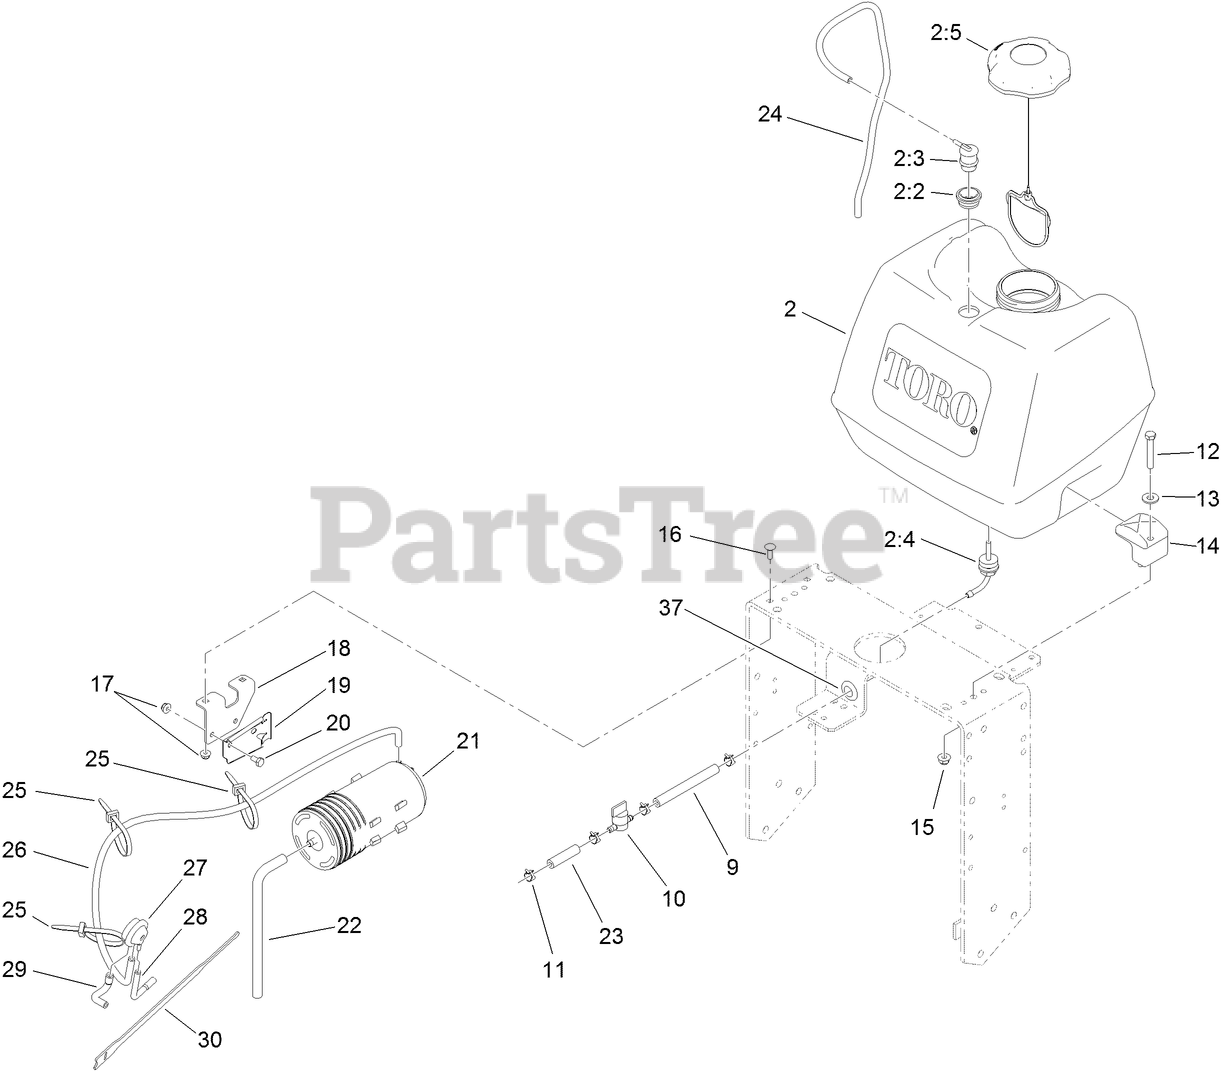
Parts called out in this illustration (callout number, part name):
2	FUEL TANK ASM
2:2	GROMMET
2:3	VALVE-ROLLOVER
2:4	FITTING-FUEL, BULKHEAD
2:5	CAP-FUEL, RATCHETING
9	HOSE-FUEL
10	VALVE-FUEL
11	CLAMP-HOSE
12	SCREW-HH
13	WASHER-FLAT
15	NUT-HF, NI
16	BOLT-CARR
17	NUT-HF
18	BRACKET-CANISTER, CARBON
19	BRACKET-CANISTER, CARBON
20	SCREW-HH
21	CANISTER-CARBON, 800CC
22	HOSE-VENT, CANISTER
23	HOSE-FUEL
24	HOSE-VENT
25	TIE-CABLE
26	HOSE-VENT, FORMED
27	VALVE-CONTROL, VACUUM
28	HOSE-VENT, FORMED
29	HOSE-VENT, FORMED
30	STRAP-VELCRO, CABLE TIE
37	GROMMET
